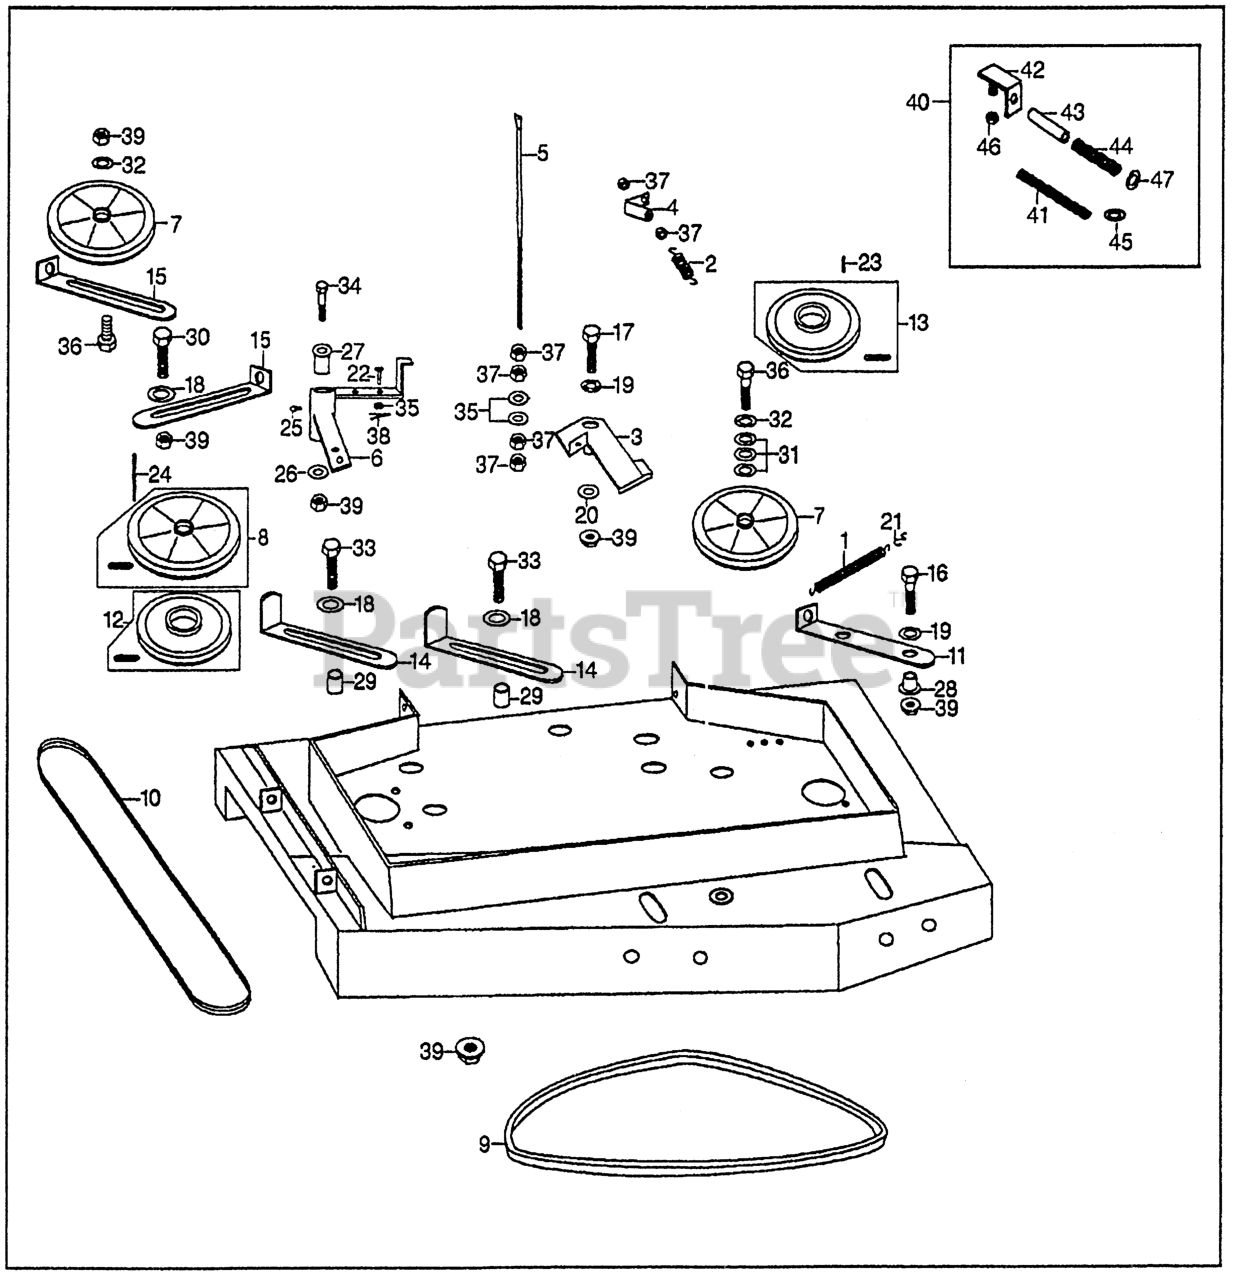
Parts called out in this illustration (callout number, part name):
1	SPRING, TENSIONER
2	SPRING, PUMP ARM
3	BRAKE ASSY.
4	BRACKET, SPRING
5	ROD C, P.T.O. (36")
6	ARM, TENSIONER
7	PULLEY A, TENSION
8	KIT, DECK PULLEY
9	V-BELT, BLADE
9	V-BELT, DECK Use up to Frame SN 1000677.
10	V-BELT, DECK Use up to Frame SN 1000677.
11	ARM, IDLER
12	PULLEY KIT A
13	PULLEY KIT B
14	GUIDE A, BELT
15	GUIDE B, BELT
16	BOLT A, SHOULDER
17	BOLT B, SHOULDER
18	WASHER
19	WASHER, BELLEVILLE (1/2") Use up to Frame SN 1000677.
20	WASHER (5/16")
21	CLIP, SPRING
22	PIN, PIVOT
23	KEY A, DRIVEN PULLEY
24	KEY, SQUARE (1/4"X1/4"X1")
25	NIPPLE, GREASE
26	BUSHING (1")
27	BUSHING, PIVOT
28	BUSHING, SNAP
29	COLLAR B, SPACER
40	BRAKE KIT, BLADE Use up to Frame SN 1000677.
41	SPRING, NEUTRAL Use up to Frame SN 1000677.
44	SPRING, TENSIONER ARM Use up to Frame SN 1000677.
45	WASHER, BELLEVILLE (1/2") Use up to Frame SN 1000677.
